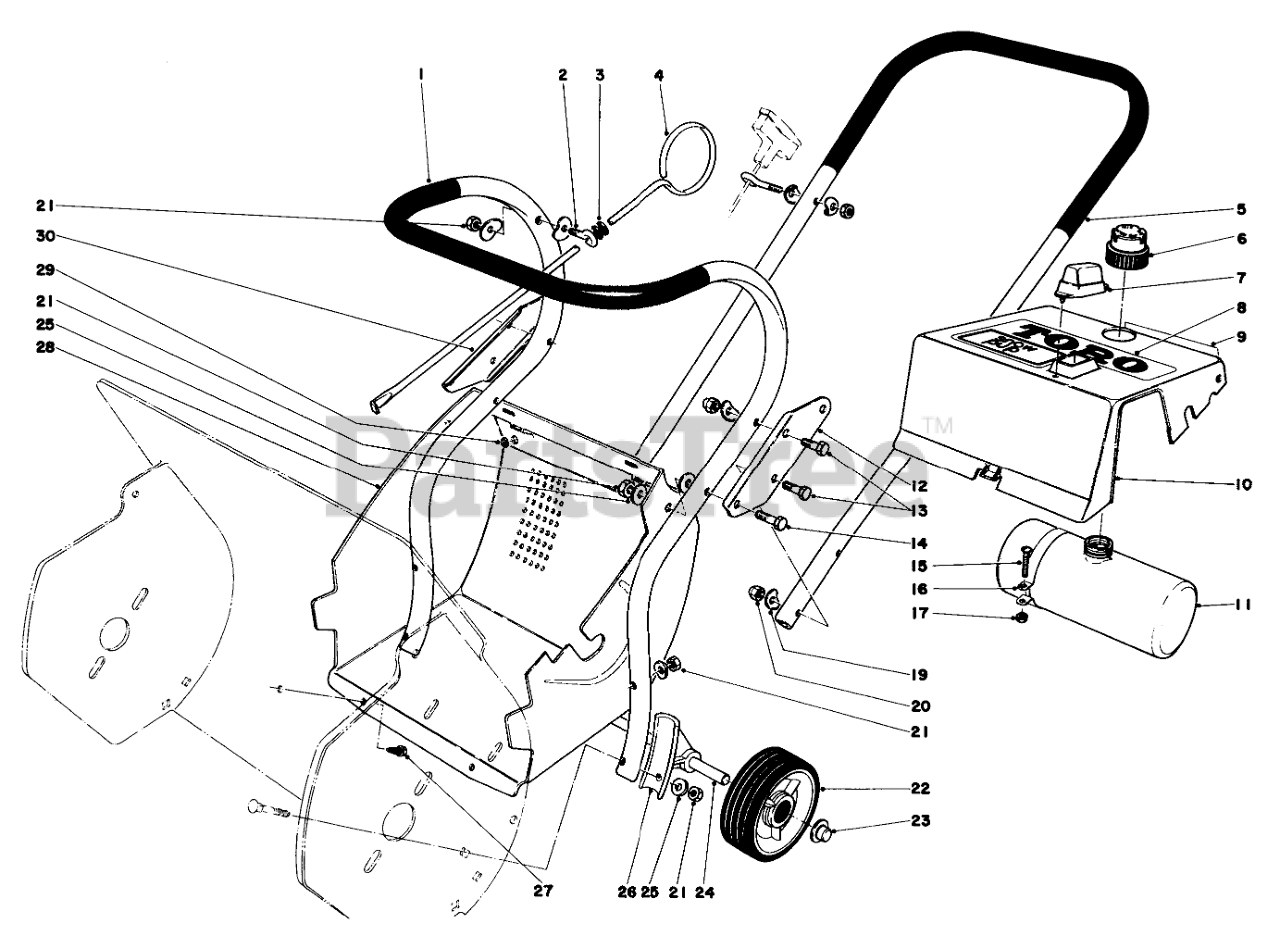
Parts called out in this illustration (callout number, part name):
1	Lower Handle
2	Bolt-Eye
3	GROMMET
4	Vane Adj. Rod
5	Upper Handle
6	Cap, Gas
8	Decal
9	Decal
10	Shroud, Upper (Incl. Ref. Nos. 7, 8 & 9)
11	Gas Tank Assembly (Incl . Ref . No. 6 & No .18)
12	SPLICE PLATE
13	Capscrew
14	SCREW-HH
15	10-24 X 1 RND HD MS
16	1/2 GAS TANK CLAMP
17	NUT-SQ
19	Washer
20	NUT-CAP
21	Nut
22	Wheel
23	RETAINER-PUSH ON
25	WASHER-FLAT
26	Wheel Bracket
27	SCREW-HWHTF
28	Lower Shroud (Incl. Ref. No. 29)
29	SNO PUP PLATED EYELET
30	Plate-Splice
